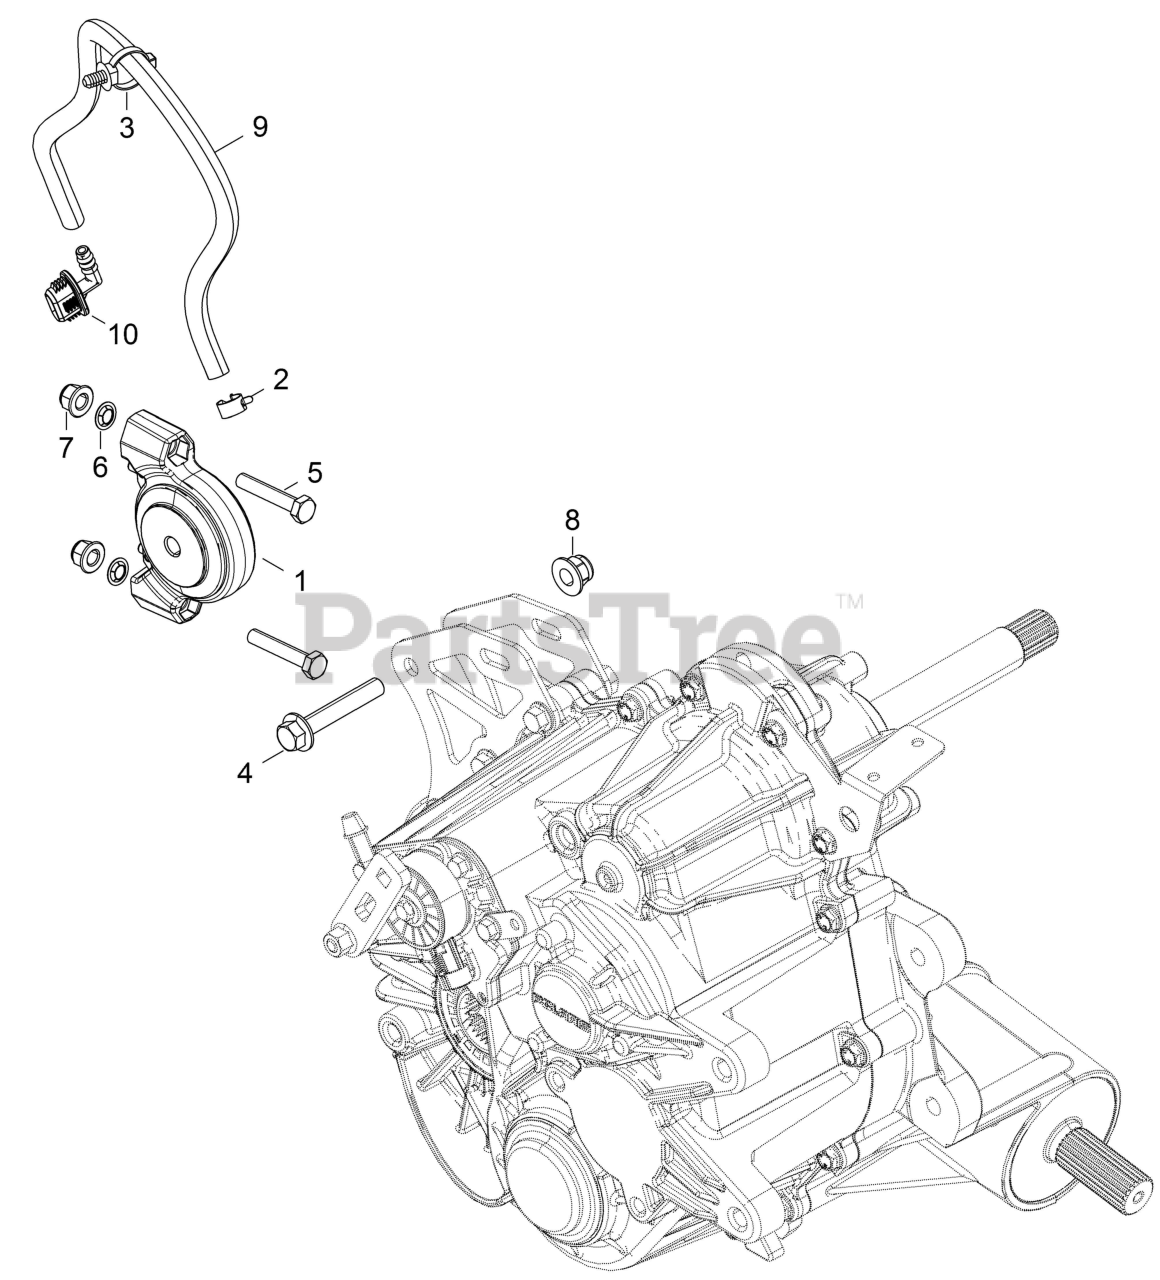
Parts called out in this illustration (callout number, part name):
1	MOUNT-ISOLATOR,DRIVELINE
2	CLAMP-HOSE, 17/32, GREEN
3	CLIP-ROUTING
4	BOLT-M10X1.25X60,HXFLG-OLIVE D
5	SCR-HH M8X1.25X45 8.8 ZOD
7	NUT-M8X1.25,FLG,NYLOC-OLIVE D
8	NUT-M10X1.25,FLG,NYLOC-OLIVE D
9	LINE, FUEL 54 CM
10	FITTING, VENT LINE, 90
